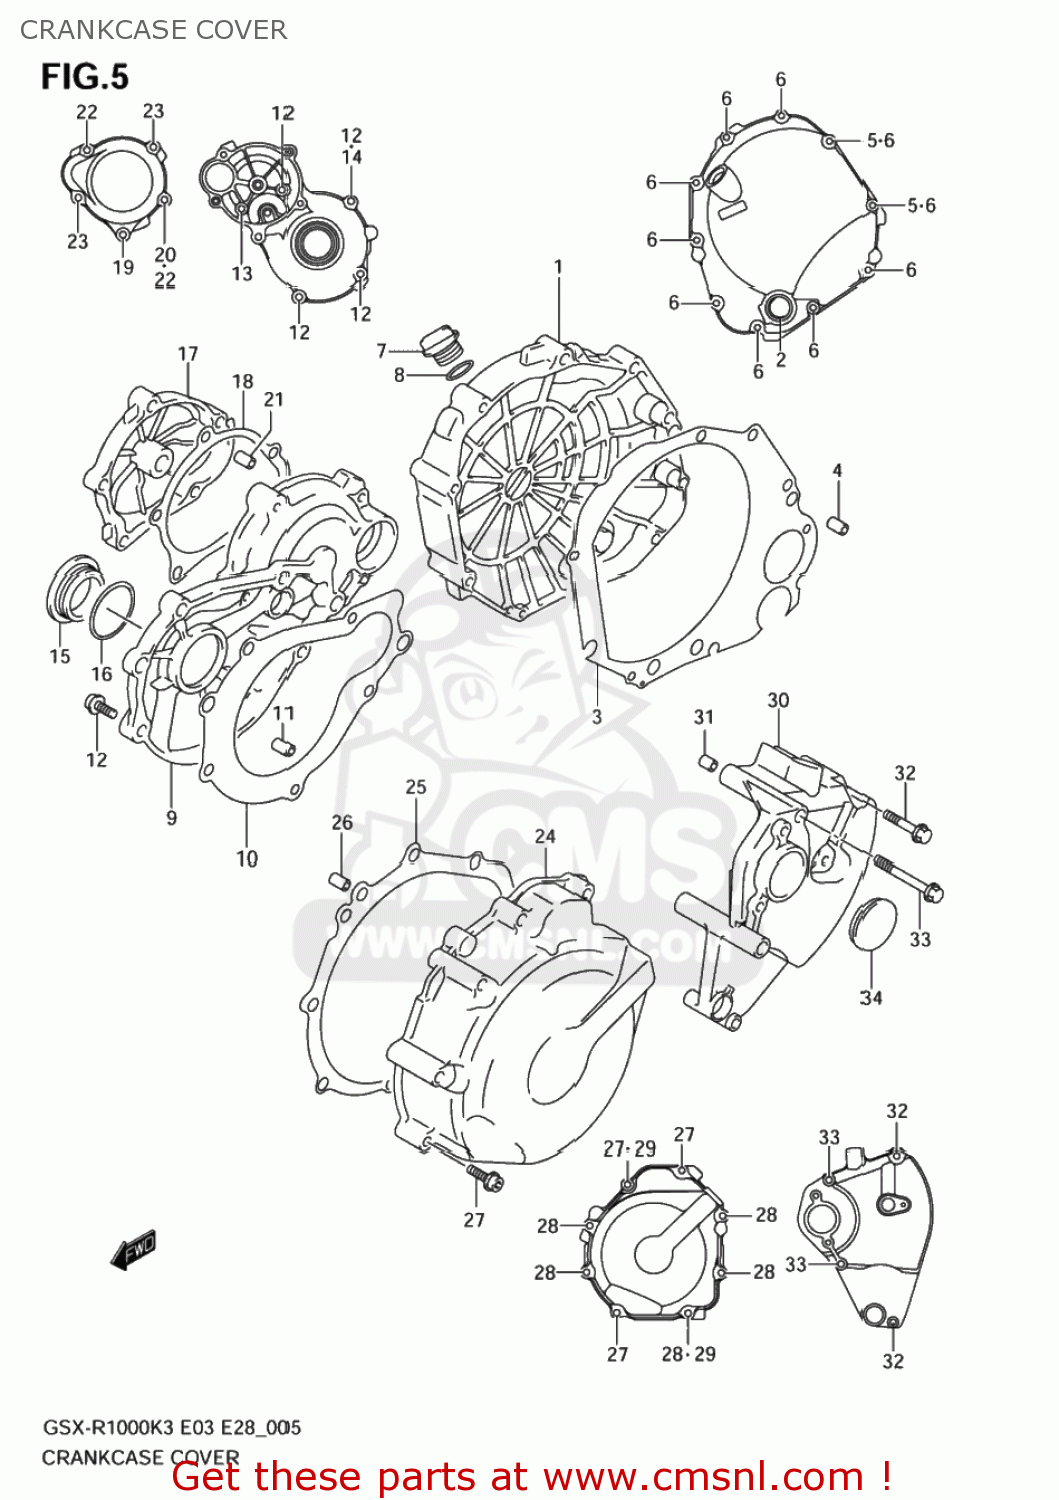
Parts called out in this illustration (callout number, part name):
1	COVER,CLUTCH
2	LENS,OIL LEVEL CHECK
3	GASKET,CL COVE (NAS)
4	PIN
5	GASKET(5.8X13X1.2) (NAS)
6	BOLT,G/S SWITC
7	PLUG,ENGINE OIL FILLER
8	O RING(D:3.1,ID:16.8)
9	COVER,STARTER CLUTCH
10	GASKET,STARTER CLUTCH COVER
11	PIN
12	SCREW
13	BOLT
14	GASKET(5.8X13X1.2) (NAS)
15	PLUG
16	O RING(D:3.1,ID:32.7)
17	CAP,STARTER IDLE GEAR
18	GASKET,START IDLE GEAR CAP (NAS)
19	BOLT
20	GASKET(5.8X13X1.2) (NAS)
21	PIN
22	SCREW
23	BOLT
24	COVER,MAGNETO
25	GASKET,MAGNETO COVER (NAS)
26	PIN
27	BOLT,G/S SWITC
28	BOLT
29	GASKET(5.8X13X1.2) (NAS)
30	COVER,ENGINE SPROCKET
31	PIN
32	BOLT
33	BOLT
34	CAP(OD:36)
